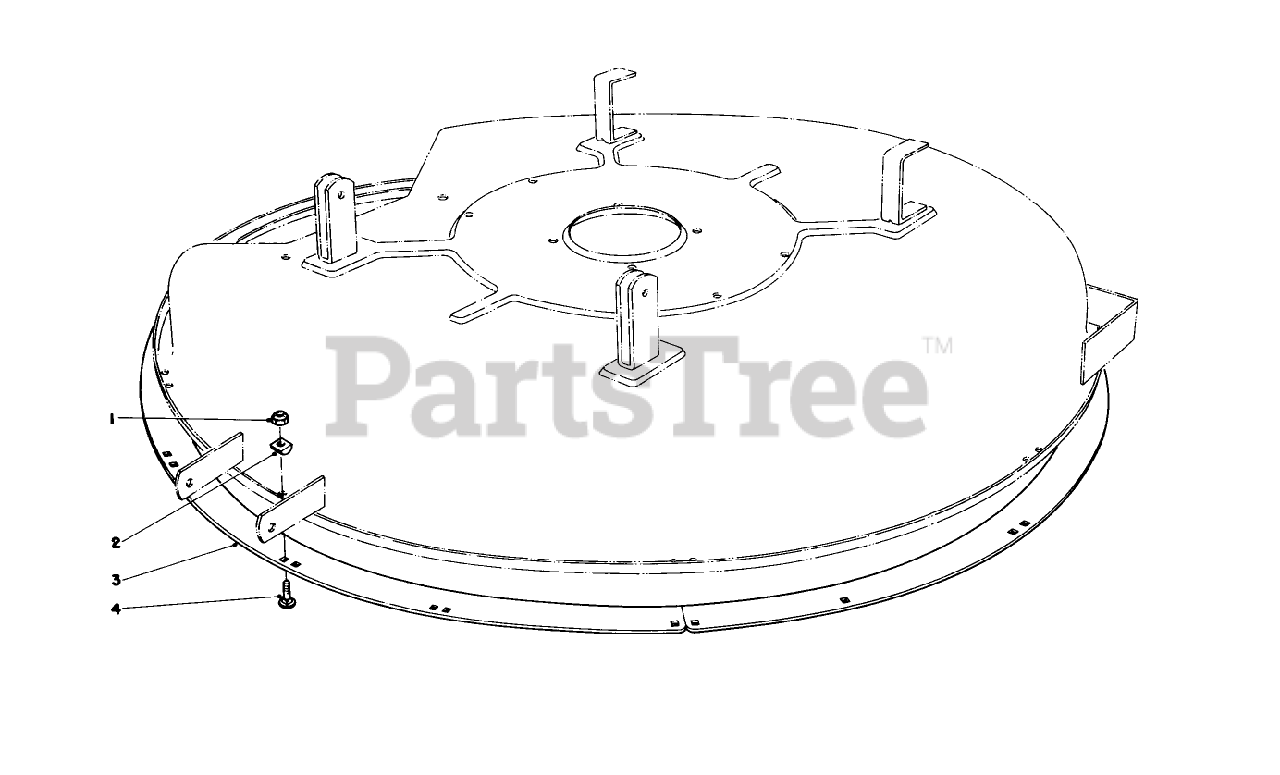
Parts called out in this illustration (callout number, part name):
1	NUT-LOCK, NI
3	DECK RING *B
4	BOLT-CARR
